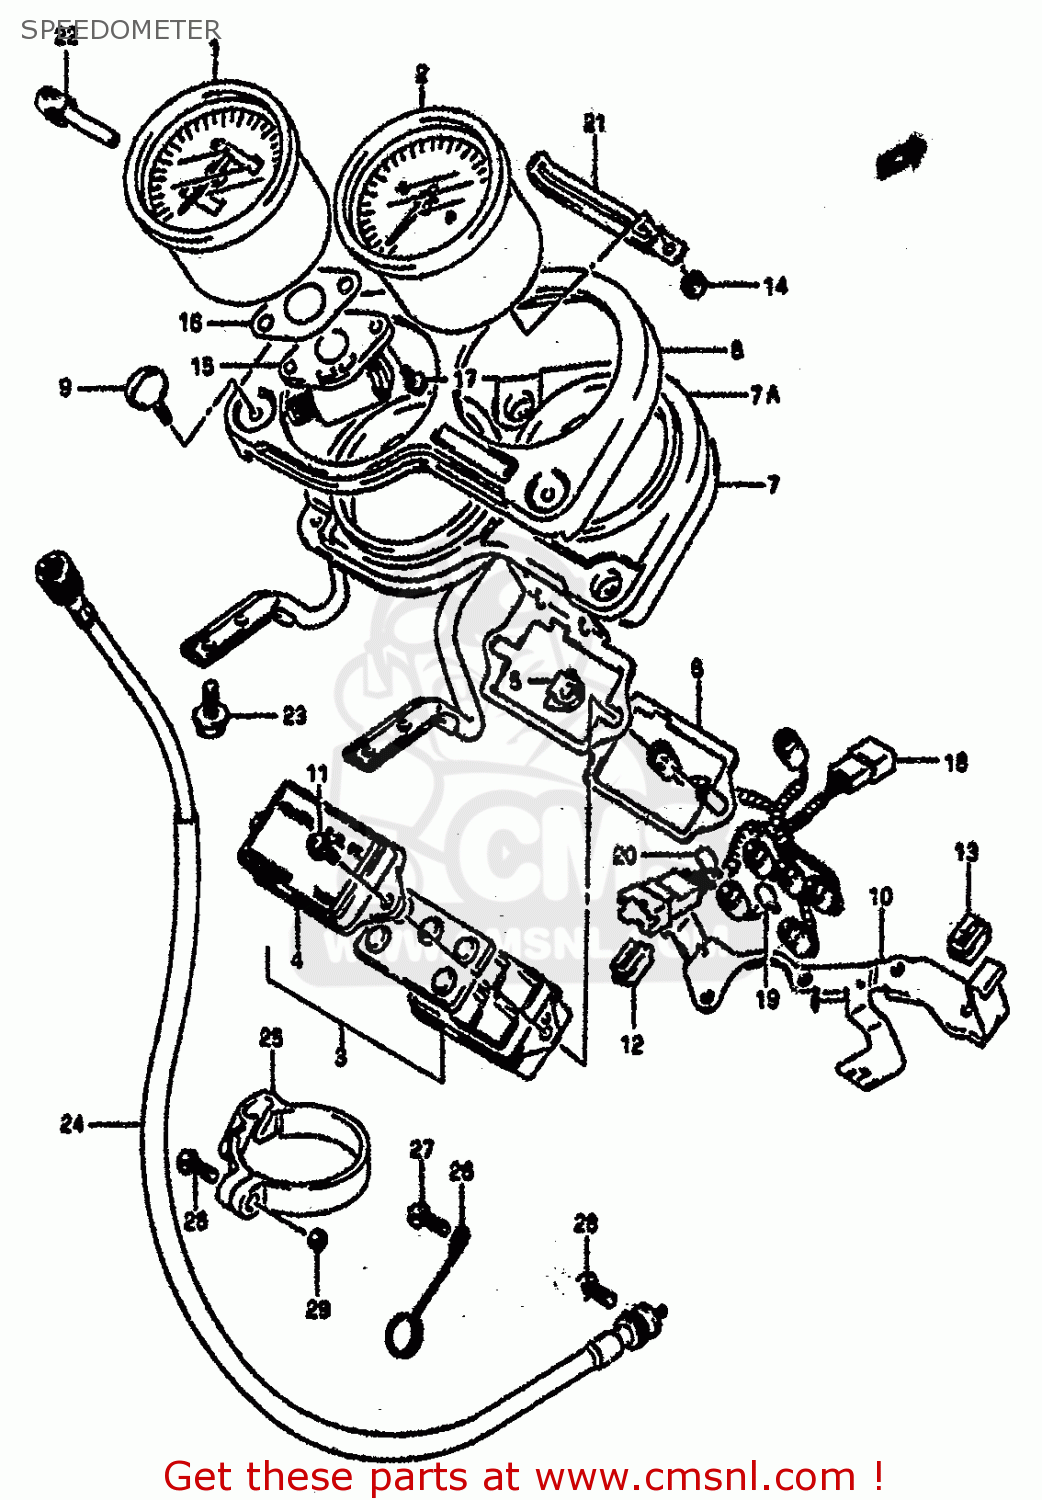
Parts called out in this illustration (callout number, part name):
1	SPEEDOMETER (KILO)
2	TACHOMETER
3	BOX ASSEMBLY,PILOT LAMP
4	LENS,BOX
5	DAMPER
6	PLATE,SETTING
7	PLATE
7A	CUSHION
8	PANEL,METER
9	BOLT,SETTING
10	BRACKET
11	SCREW
12	DAMPER,LEFT
13	CUSHION
14	NUT
15	GEAR BOX
16	GASKET,METER GEAR BOX (NAS)
17	SCREW
18	SOCKET
19	BULB(12V3W,T6.5)
20	BULB(12V1.7W,T6.5)
21	CLAMP
22	KNOB,TRIP
23	BOLT 6X12
24	CABLE ASSEMBLY,SPEEDOMETER
25	GUIDE,METER CABLE NO.2
26	GUIDE,SPEEDOMETER CABLE NO.3
27	SCREW
28	SCREW
29	NUT 5MM
